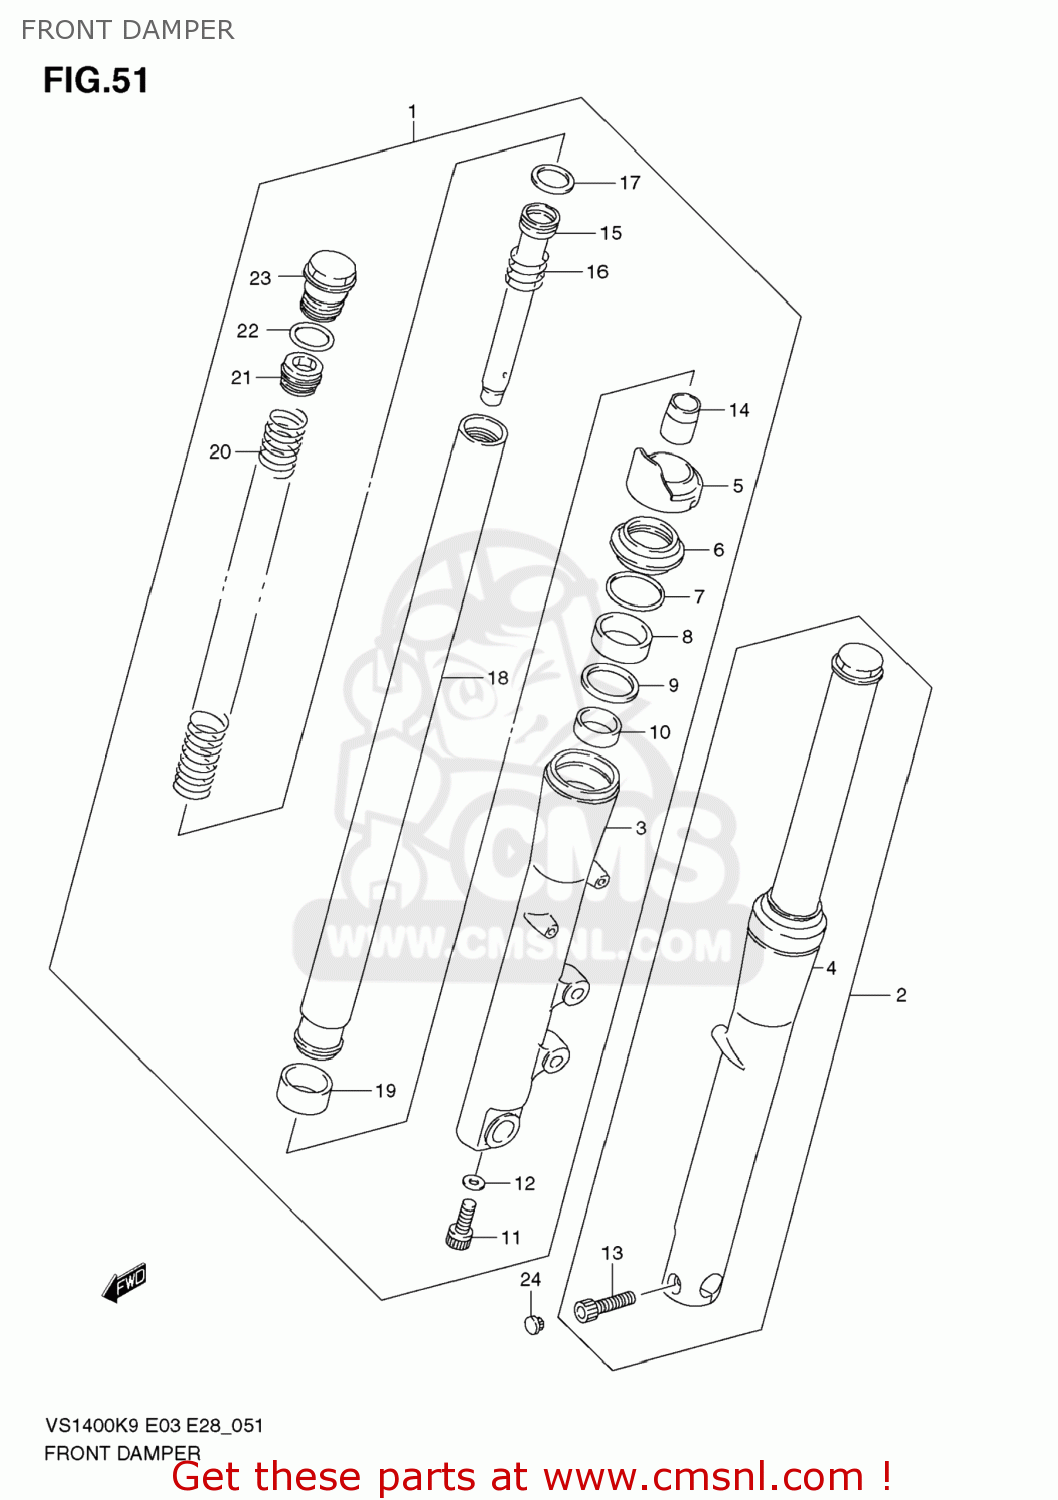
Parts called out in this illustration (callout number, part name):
1	DAMPER ASSY,FR FORK,R
2	DAMPER ASSY,FR FORK,L
3	TUBE,OUTER,R
4	TUBE,OUTER,L
5	COVER,UPR,R
6	DUST SEAL
7	CIRCLIP,FORK OIL SEAL
8	SEAL,OIL
9	SPACER,SEAL
10	BUSH,GUIDE
11	BOLT(8X27)
12	GASKET (NAS)
13	BOLT
14	PIECE,OIL LOCK
15	CYLINDER
16	SPRING,REBOUND
17	RING,PISTON
18	TUBE,INNER
19	BUSH,SLIDE
20	SPRING,FR FORK
21	BOLT,FORK INNER
22	O RING
23	BOLT
24	CAP(OD:14.5)
